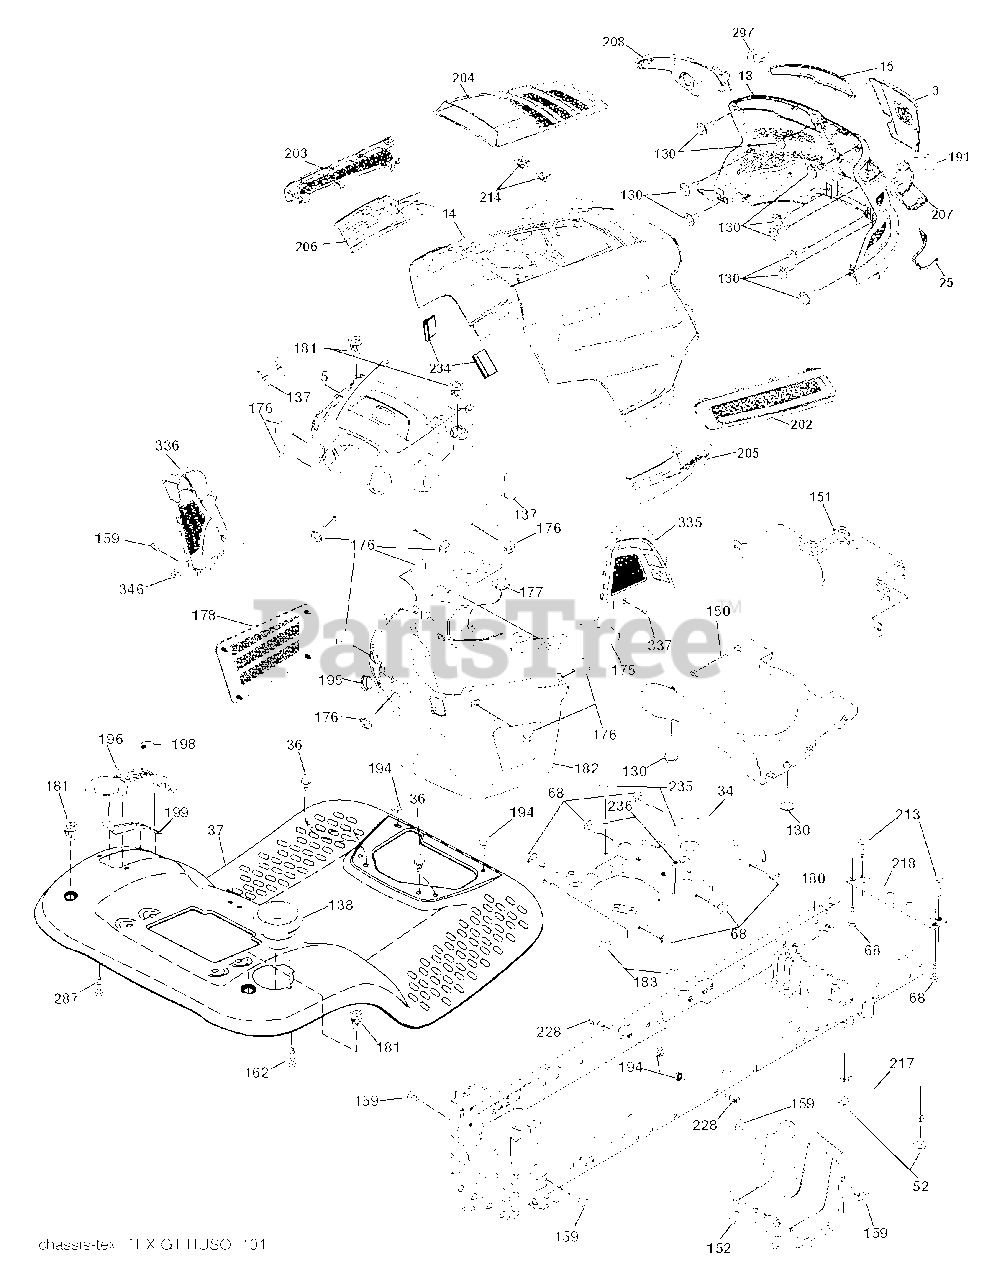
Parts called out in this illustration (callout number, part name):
3	APPLIQUE.SUBASM.GT.HUSQ.II
5	RP.DASH.UPP.GT2.SM.MC.CHOKE
14	HOOD.ASM.HUSQVARNA.GT.TEX.422
15	LENS.HEADLIGHT.LH.GTII.2011
18	GRILLE.SUBASM.GT.HUSQ.II
25	LENS.HEADLIGHT.RH.GTII.2011
34	PLATE.ENGINE.WELDED.CHASSIS
36	SCREW 5/16"
37	FENDER
52	LOCKNUT
68	SCREW LT
130	SCREW.#10 X 0.750.BOS
137	BUMPER DASH
138	HOLDER.CUP.LT.GREY
150	AIR.DUCT.GTV.BLACK
151	BRACKET.PIVOT.HOOD.GT.HUSQ.II
152	SHIELD.BROWNING.PNT.GT.V2
159	SCREW, 3/8-16X3/4
162	SCREW.HI-LO.CONSOLE
175	PLATE.CROSSMEMBER.HUSQ
176	SCREW.#10-24X5/8.RN.QU
177	BUSHING, STEERING
178	CARGO.ASM.NET.TXGT.W/C
180	CHASSIS
181	BUSHING.MNT.FEND.CRGO.TEX.49
182	DASH.LOWER.COMMON.12V.ADAPTOR
183	BOLT.5/16-18X1-1/4 FULL THD
191	INSERT.REFLECTIVE.RH.HUSQ.GTII
194	NUT LOCK HEX FLANGE 5/16-18
195	PLUG.HOLE.DASH.LOWER.12V.BLK
196	DECKLFT.CONSOL FULL ASSM GREY
198	INDICATOR.DECK.LIFT.RED
199	PLATE.DECK.LIFT.HUSQ.LT
202	VENT.SIDE.RH.GT.HUSQ.II.
203	VENT.SIDE.LH.GT.HUSQ.II.498
204	VENT.TOP.HUSQ.GT2
205	SIDE.TRIM.RH.GT.HUSQ.II
206	SIDE.TRIM.LH.GT.HUSQ.II.GRAY
207	BEZEL LIGHT.RH.GT.II.MYLAR
208	BEZEL LIGHT.LH.GT.II.MYLAR
213	BOLT
214	CLIP.RETAINER.TINNER.
217	ROD.PIVOT.HOOD
218	X-PIECE.HOOD.STOP.NON/
228	STUD.FASTNER.W/ANTI-ROTATE
234	BUMPER.HOOD.TEX.HUSQVARNA
235	SPACER FENDER
236	NUT.CENTERLOCK.5/16-
287	SCREW 1/4X20
297	INSERT.REFLECTIVE.LH.HUSQ.GTII
335	COVER.RH.CLOSE.OUT.BLACK
336	COVER-LH.LOWER.DASH.GT2.BLACK
337	CLIP.XMAS.TREE.ITW.2622-00
346	CLIP,INSULATOR
